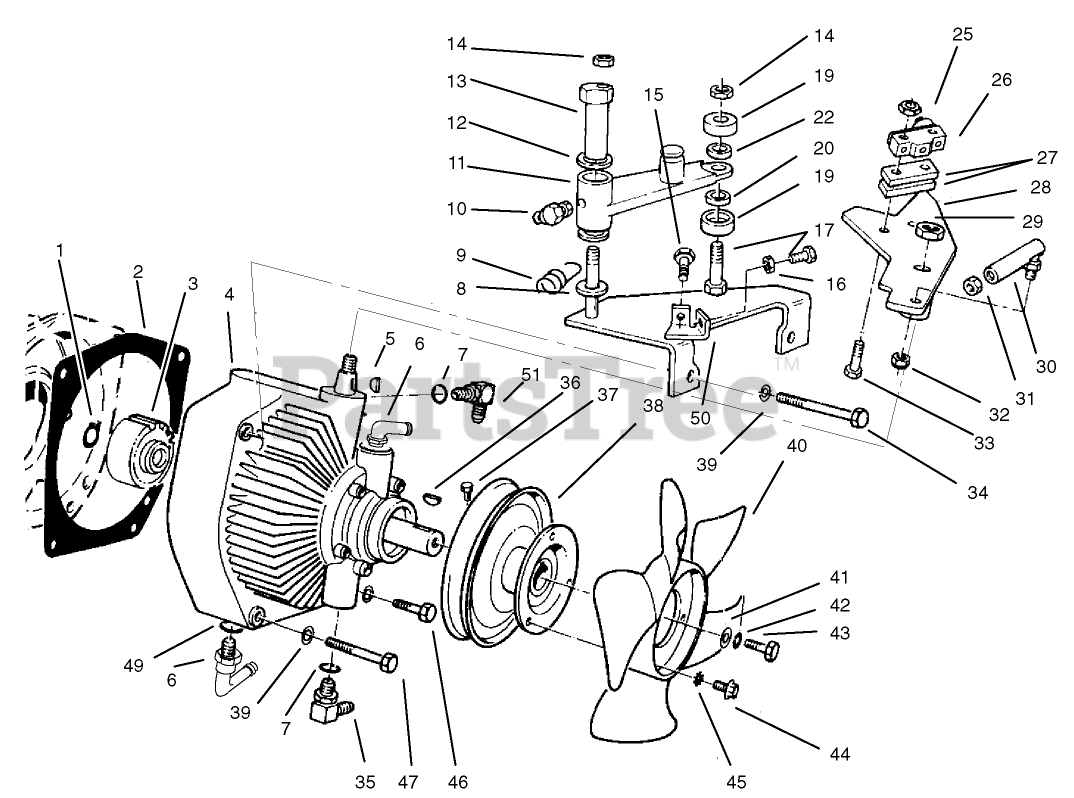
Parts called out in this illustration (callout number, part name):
1	RING-SNAP, EXTERNAL
2	TRANS GASKET
3	GEAR-SPUR
4	TRANSMISSION - HYDRO
5	KEY-WOODRUFF
6	ADAPTER
7	O-RING
8	WASHER-FLAT
9	SPRING-EXTENSION
10	FITTING-GREASE
11	Swing Arm Assembly (Incl. 256-113 Bushings (2)
12	WASHER-THRUST
13	STUD-TRACTION
14	NUT-LOCK, NI
15	SCREW-HH
16	NUT-HEX
17	SCREW-HH
19	BEARING-BALL
20	SPACER
22	SPACER-BEARING
25	NUT-HEX
26	SWITCH-MICRO
27	PLATE-SWITCH
28	Lever-Traction
29	NUT-LOCK, NI
30	JOINT-BALL
31	NUT-JAM
32	NUT-LOCK
33	SCREW-PPH
34	SCREW-HH
35	Fitting-Hydraulic, 905 (Incl. Ref. #7)
36	KEY-WOODRUFF
37	SCREW-SQH
38	TRANS PULLEY
39	WASHER-LOCK
40	FAN 8"
41	WASHER-FLAT
42	WASHER-LOCK
43	SCREW-HH
44	SCREW-SHWH
45	WASHER-LOCK/EXT
46	SCREW-HH
47	SCREW-HH
49	O-RING
50	Plate-Traction
51	FITTING-ELBOW-90 DEG
